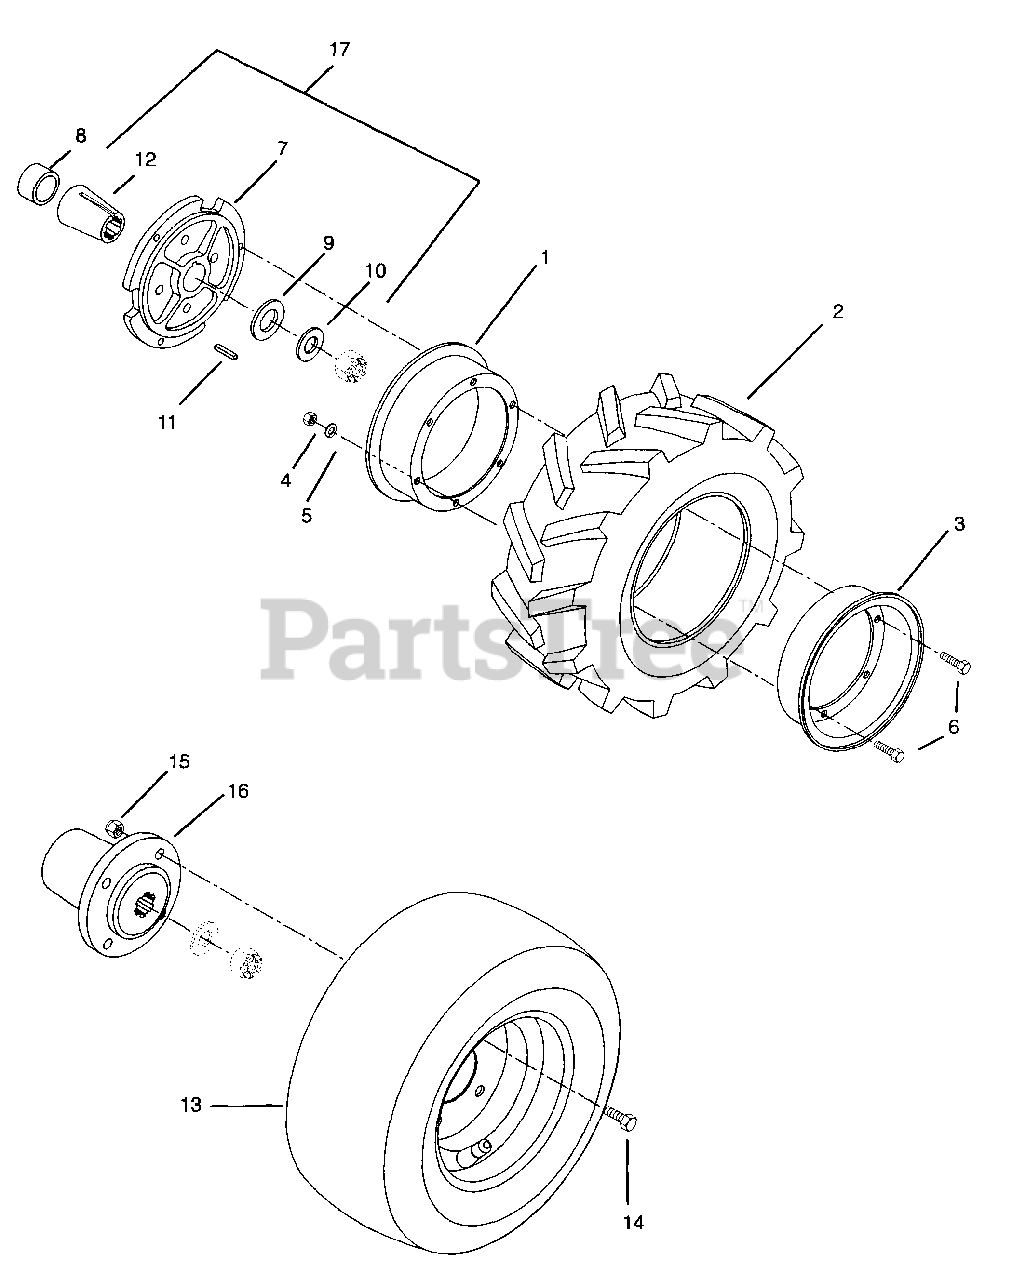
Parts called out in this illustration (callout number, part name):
1	Wheel 7.71 x 1.25
2	Tire 16 x 5W x 3
3	Wheel - Disc 6.75 x 9.219
4	Nut-Hex .38-16
5	Washer-Lock .375 x .094
6	Bolt-Hex .38-16 x .75 Grade 5
7	Hub, Wheel
8	Bushing, Sleeve 1.02 x 1.37 x 1.13
9	Washer-Flat-Steel 2.0 x 1.12 x .148 Hardened
10	Washer-Flat-Steel .688 x 1.75 x .134
11	Key-Square .249 x 1.25 x .248
12	Insert, Hub
13	Tire/Wheel Assembly 8.50-8 x 18
13	Tire/Wheel Assembly 4.80/4.00-8
13	Tire/Wheel 4.80/4.00-8
14	Bolt-Hex .50-13 x 1.50 Grade 5
15	Nut-Locking-Center .50-13 Grade 5
16	Hub, 7" Wheel
17	Three Bolt Heavy Hub Kit
